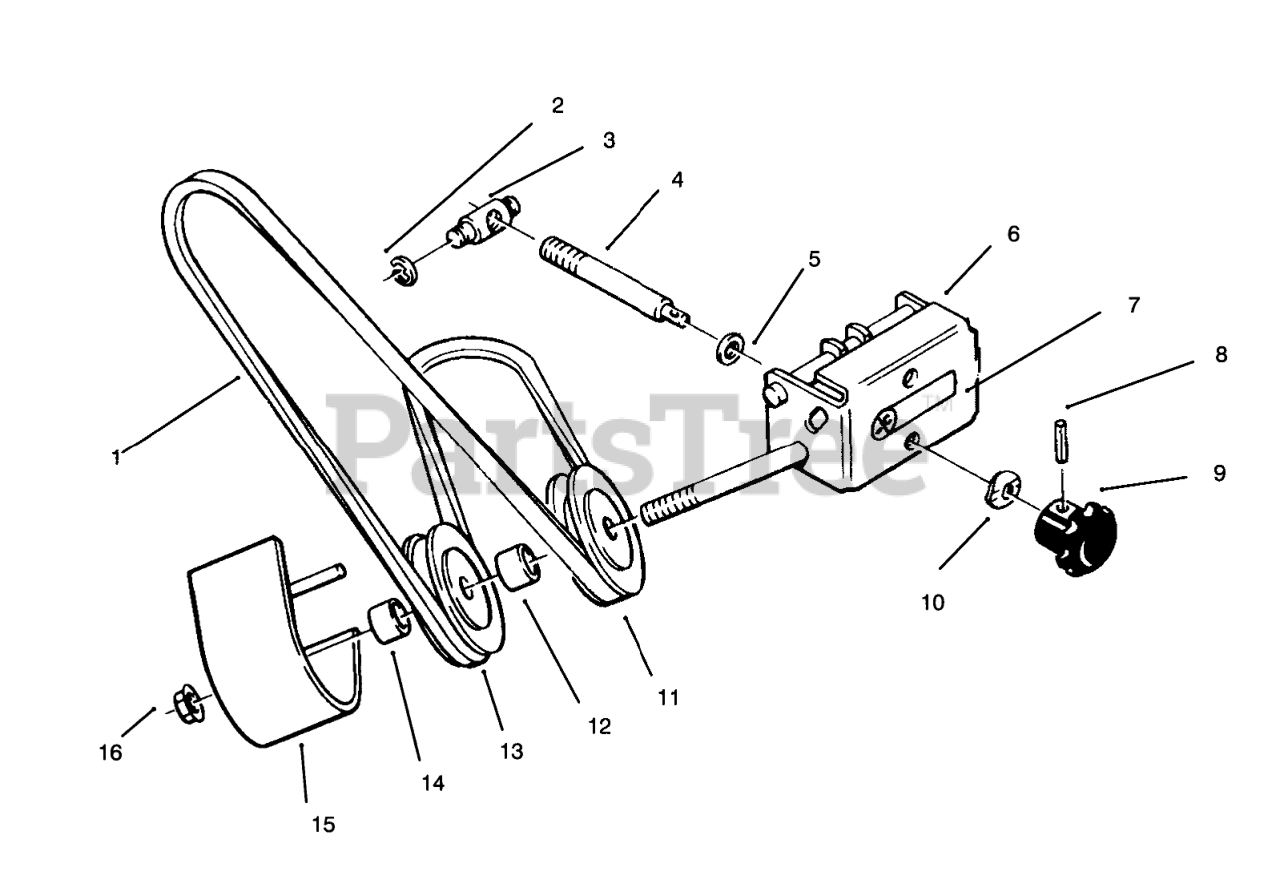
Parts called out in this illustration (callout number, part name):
1	V-BELT
2	RING-RETAINING
3	TRUNNION-DOUBLE
4	ROD ADJ
5	Washer
6	Front Support
7	Decal-Attac-O-Matic
8	PIN-ROLL
9	KNOB-ADJUSTMENT
10	WASHER-SPRING
11	Pulley-V
12	SPACER
13	PULLEY-FLAT IDLER
14	SPACER-OUTER
15	Belt Cover
16	Nut
